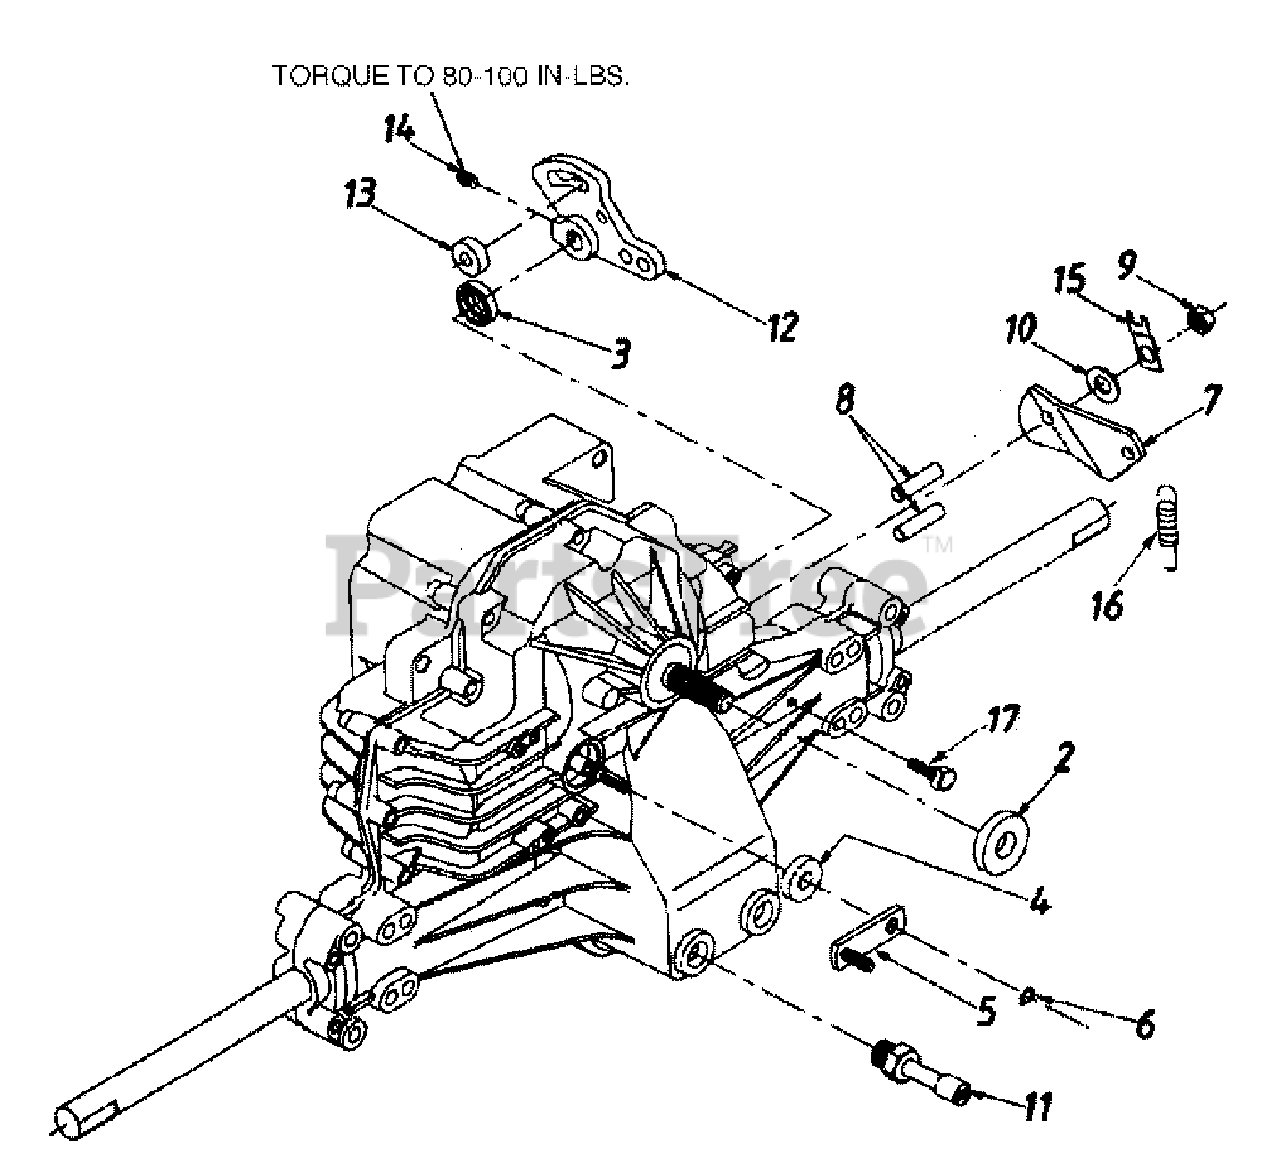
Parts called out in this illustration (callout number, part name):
4	Seal-Lip 10 x 25 x 7
6	Ring-Retaining
7	Arm-Actuating
8	Pin-Actuating
9	Nut-Hex Lock 5/16-24 UNJC
10	Washer 7/16" x 7/8" x .060"
11	Breather Ass'y.
13	Puck-Dampener
15	Strap, Locking
16	Spring, Extension
17	Self Tapping Screw #10-32 x .5"
